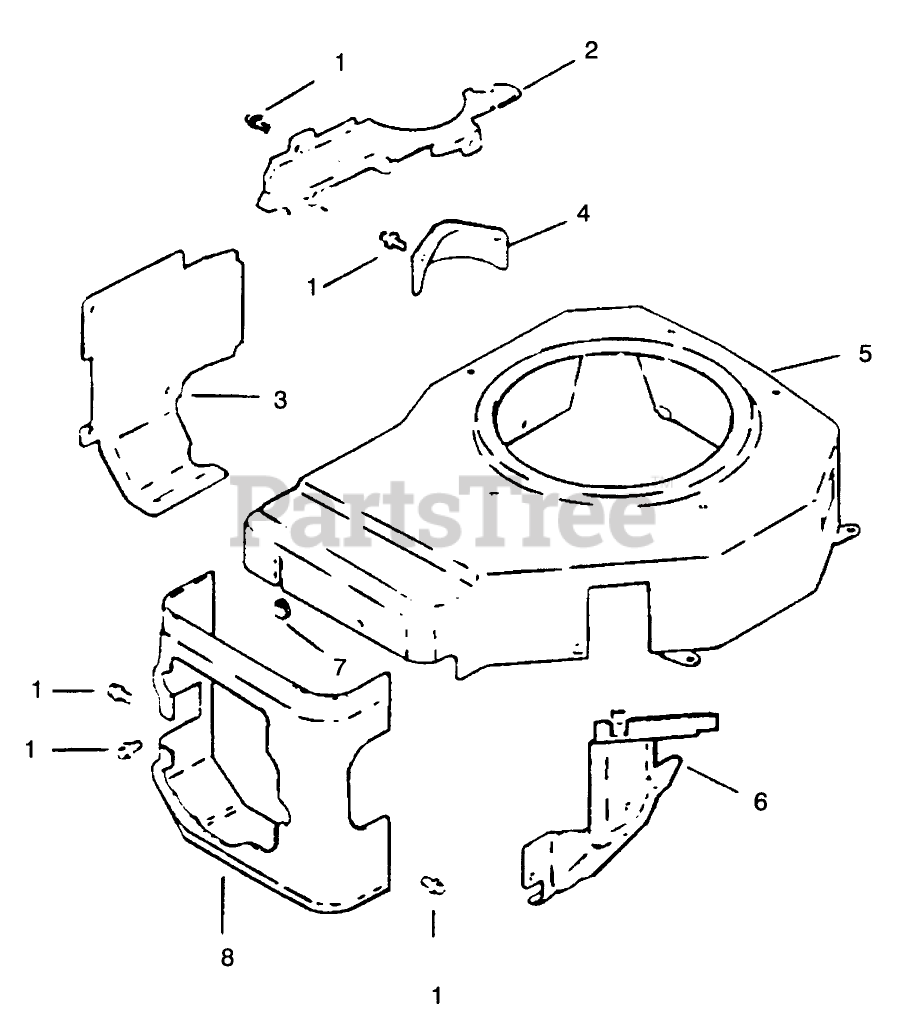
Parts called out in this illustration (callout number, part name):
1	Screw
2	Plate-Blower Housing
3	Baffle-Cylinder
4	Cover-Starter
5	Housing-Blower
6	Baffle-Carburetor
7	Grommet-Blower
8	Baffle-Cyl. Head
